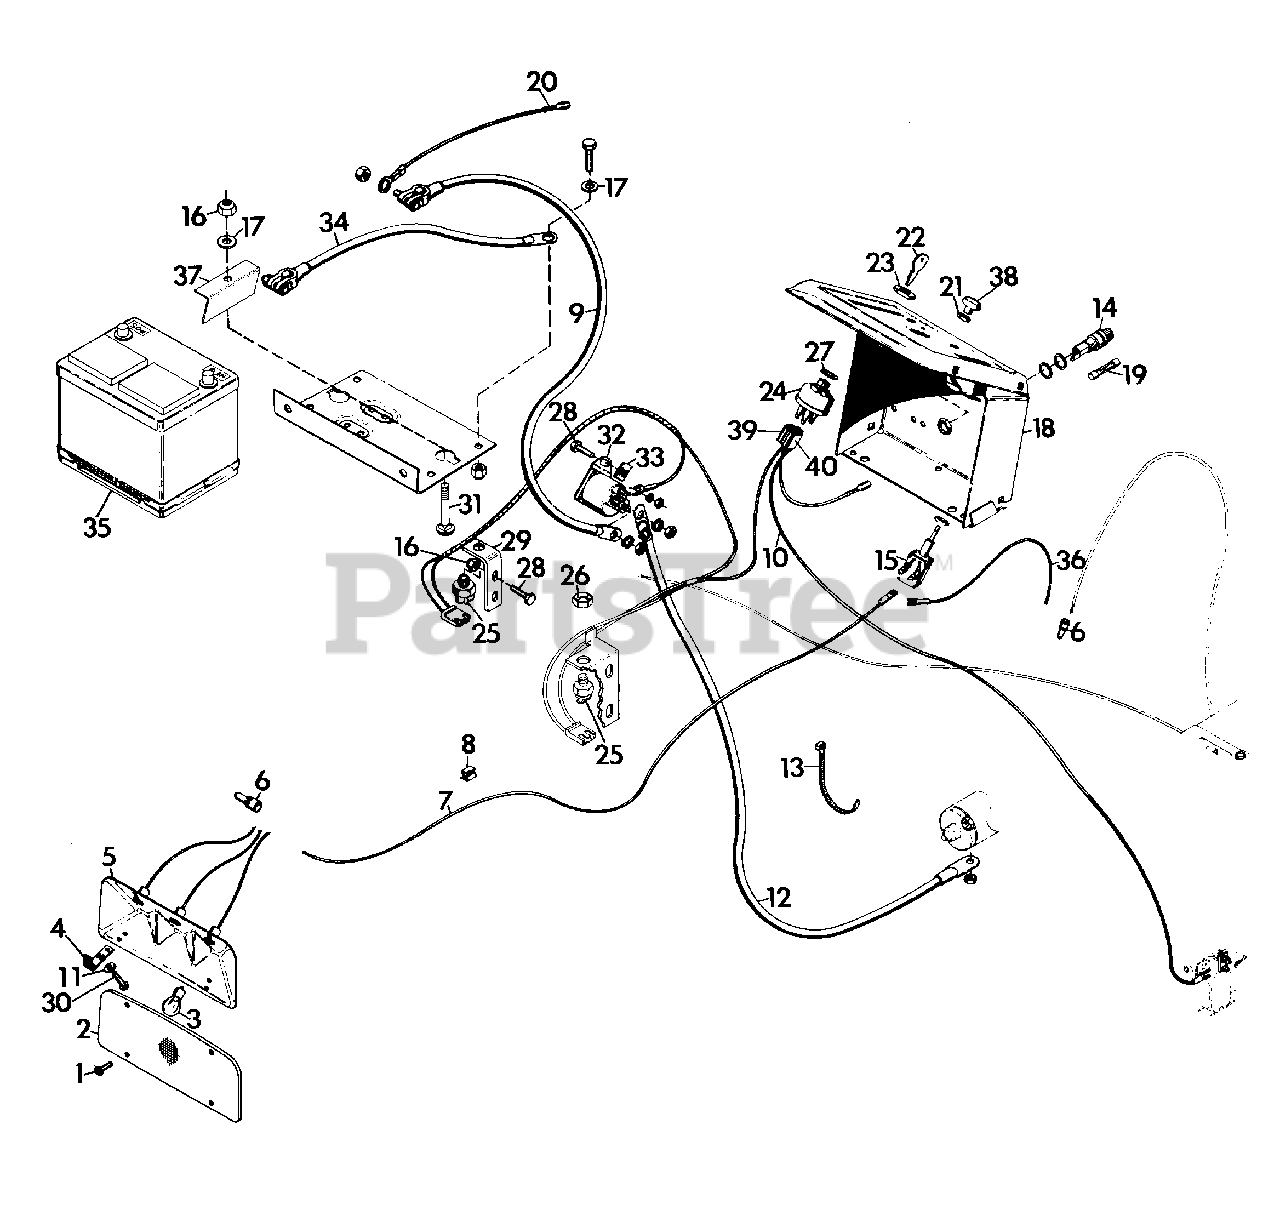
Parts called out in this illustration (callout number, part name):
1	SCREW, MACH. 10-24X.50 PHD
2	PANEL, FRONT LIGHT
3	LAMP, NO. 1073
4	CLIP, LIGHT MTG.
5	ASSEMBLY, LAMP REFLECTOR
6	NUT, WIRE
7	WIRE, HEADLIGHT
8	CLIP, WIRE
9	CABLE, BATTERY TO MAGNETIC SWITCH
10	HARNESS, WIRING 16 BP B & S
11	WASHER, FLAT .188X.562X.049
12	CABLE, STARTER
13	TIE, CABLE
14	FUSE, PANEL
15	SWITCH, LIGHT
16	NUT, LOCK 1/4-20
17	WASHER, FLAT .281X.625X.065
18	PANEL, INSTRUMENT
19	FUSE, 30 AMP AGC 30
20	WIRE, INSTRUMENT PANEL
21	NUT, SPECIAL
22	KEY, IGNITION SWITCH
23	NUT, JAM 9/16-24
24	SWITCH, IGNITION
25	SWITCH, INTERLOCK
26	NUT, STAMPED 9/16-18
27	WASHER, LOCK INT. TOOTH
28	BOLT, HEX 1/4-20X.625
29	BRACKET, SWITCH
30	SCREW, MACH. 10-24X.75 PHD
31	BOLT, 1/4-20X1.75 RD HD SQ NK
32	SWITCH, MAGNETIC
33	NUT, SPEED 1/4-20
34	CABLE, NEGATIVE BATTERY
35	BATTERY, 12 VOLT
36	WIRE, HEADLIGHT
37	CLAMP
38	KNOB, LIGHT SWITCH
39	CONNECTOR
40	TERMINAL
NS	WASHER, LOCK 1/4 EXT. TOOTH TYPE A
NS	BOOT, BATTERY CABLE
